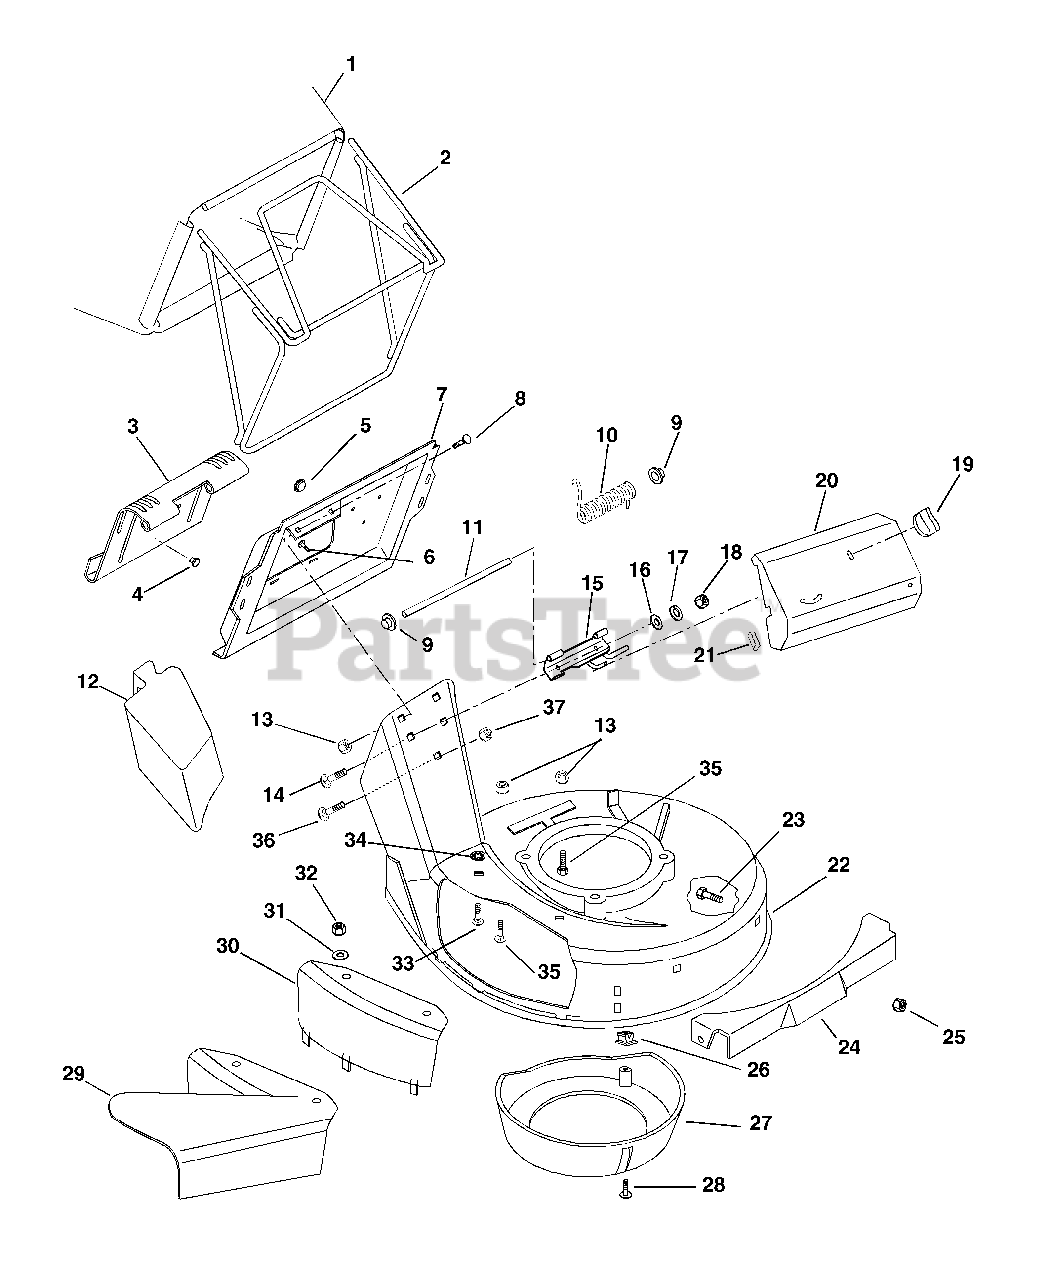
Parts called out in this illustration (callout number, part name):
1	BAG, CONSUMER BLACK 15 OZ/YD2
2	FRAME, BAGGER
3	CATCHER PLATE DOOR
4	BUTTON BUMPER
6	SCR-TAP 10-24X.375 TORX PHD YZ
7	PLATE, CATCHER
8	@BLT-RHDSSQNK .25-20X.38 G2YZ
9	PUSH NUT, .25
10	SG-TORS .120X.68X3.09
11	DOOR PIN
12	MULCH MASTER MULCHER ACCESSORY
13	@NUT-SPNLK-FLG .25-20 YWZC
14	@BLT-RDHDSQNK .25-20X.75 G5YZ
15	HINGE BASE WELDMENT
16	WSHR-FL-STL .328X.87X.179 YWZC
17	WSHR-LK .250X.077 HVY YWZC
18	@NUT-HEX .25-20 YWZC
19	WING - NUT
20	COVER, DRIVE
21	TRIM BUMPER
22	PAN-MOWER W/DECALS COM 3SPD
23	@BLT-RDHDSQNK .31-18X.50 G5YZ
24	PANEL-FRONT, 3 SPD
25	@NUT-SPNLK-FLG .312-18 YWZC
26	PLASTIC GROMMET
27	CENTER BAFFLE
28	SCR-TAP 10-16X.62 SLPH AB YWZC
29	SIDE DISCHARGE ASSEMBLY
30	COVER, SIDE DISCHARGE
31	@WSHR-FL-STL.406X.812X.065 YWZ
32	@NUT-LK-NYL .312-18 YWZC
33	BLT-RDHDSQSHK.31-18X.75 GR2 YW
34	NUT-PUSH .312
35	@BLT-HEX .25-20X.50 GR5 YWZC
36	@BLT-HEX .38-16X.50 GR5 YWZC
37	@NUT-SPNLK-FLG .375-16 YWZC
